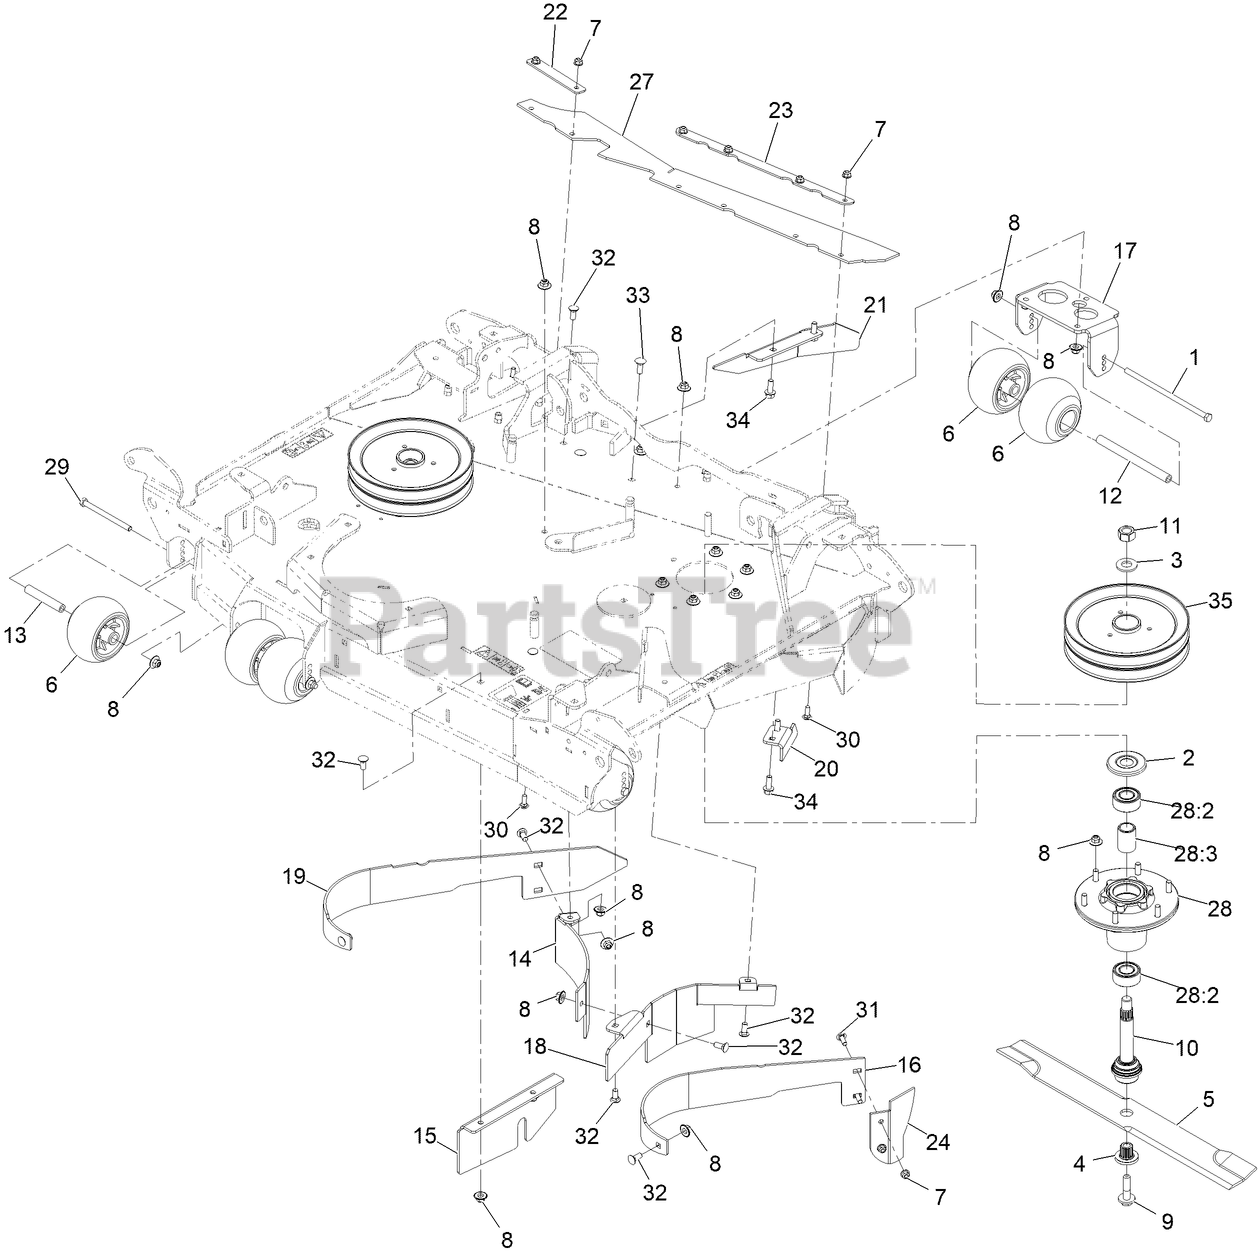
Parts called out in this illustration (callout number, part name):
1	SCREW-HH
2	GUARD-BEARING, TOP
4	BUSHING,SPLINED
6	ROLLER-SCALP, ANTI
7	NUT-HF, NI
8	Nut-Nyloc 3/8-16 Flg
9	SCREW,SEMS 1/2-20 X 2.19
10	ASM-SPINDLE AND SEAL
11	NUT-HEX
12	SPACER-WHEEL
13	SPACER-WHEEL SHORT
14	BAFFLE-CENTER, REAR (RH)
15	PLATE-BLOCK, FRONT
16	BAFFLE-DOGLEG, CENTER (LH
17	BRACKET-ANTISCALP, REAR
18	BAFFLE-CENTER
19	BAFFLE-DOGLEG, CENTER (RH
20	BAFFLE-BREAKER
21	PLATE-FIN, DISCHARGE
22	SUPPORT-FLAP, LH
23	SUPPORT-FLAP, LH
24	GUARD-DISCHARGE
27	FLAP-DISCHARGE
28	ASM-CUTTER HSG
28:2	BEARING-3205 TRASHGUARD
28:3	SPACER-BEARING
29	SCREW-HH
30	SCREW-CARR
31	SCREW-CARR
32	BOLT-CARR
33	BOLT-CARR
34	SCREW-HHF
35	SHEAVE-DOUBLE 96RD
